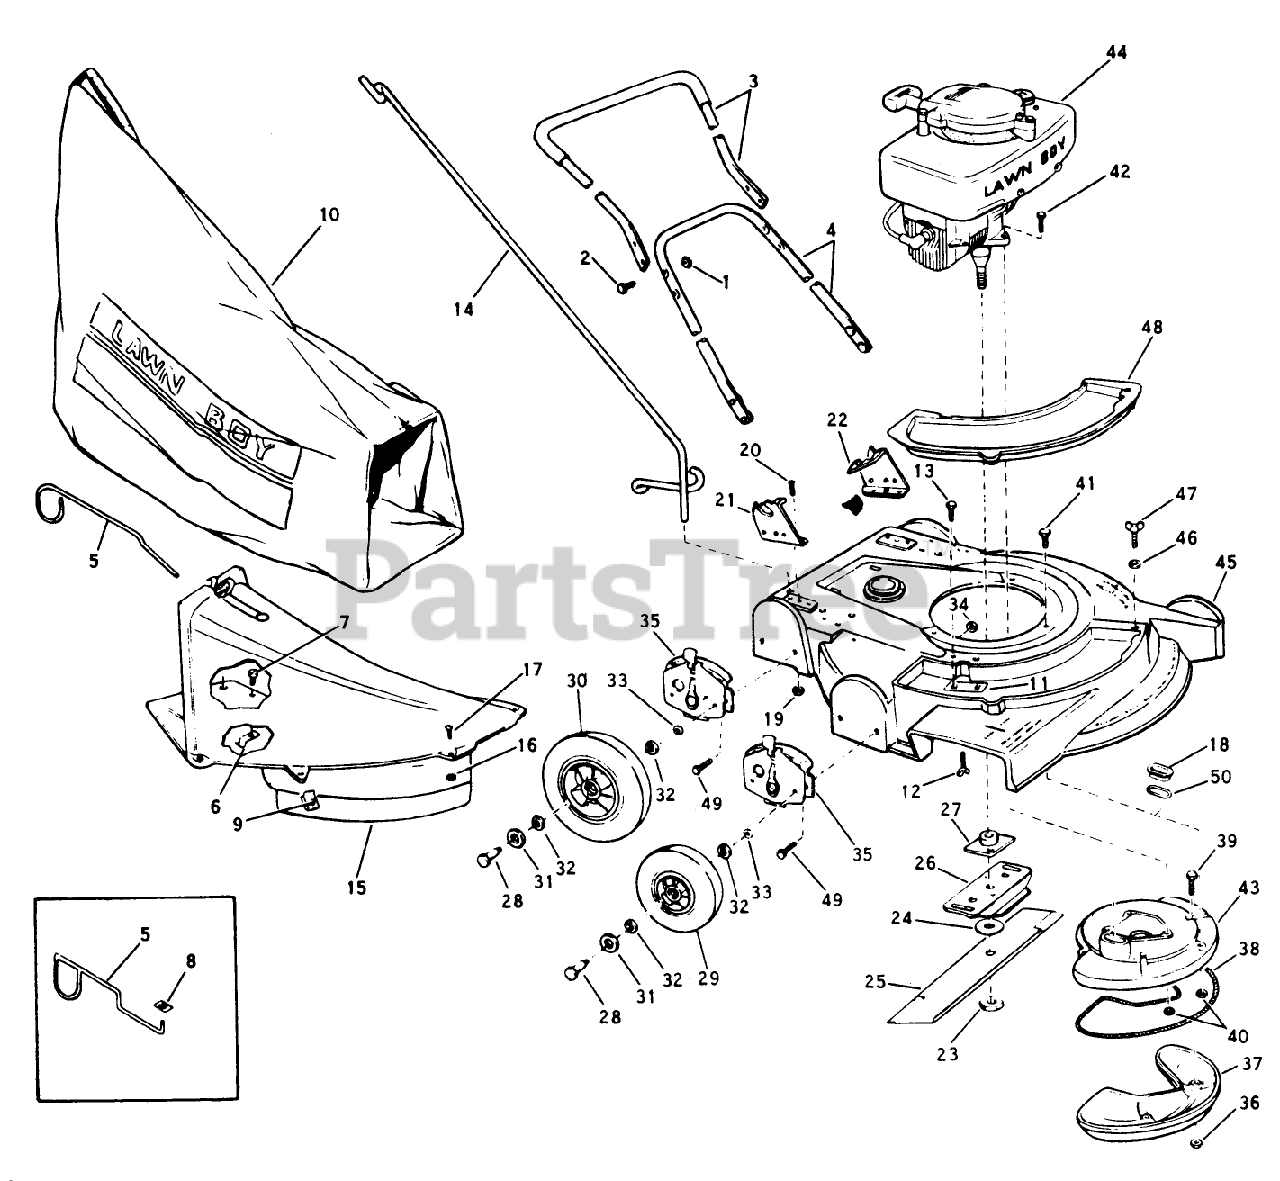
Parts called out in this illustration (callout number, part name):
3	Handle Grip Assy. Top
9	SPEED NUT ARDEN
10	89802 LB WHOLE GOODS
15	Chute Skirt Assembly (Includes Hardware)
23	NUT-BLADE
27	PLATE AND COLLAR ASM
28	BOLT WHEEL
33	WASHER WROUGHT
36	LOCKNUT E
44	Engine-Model C-18
50	GASKET S
